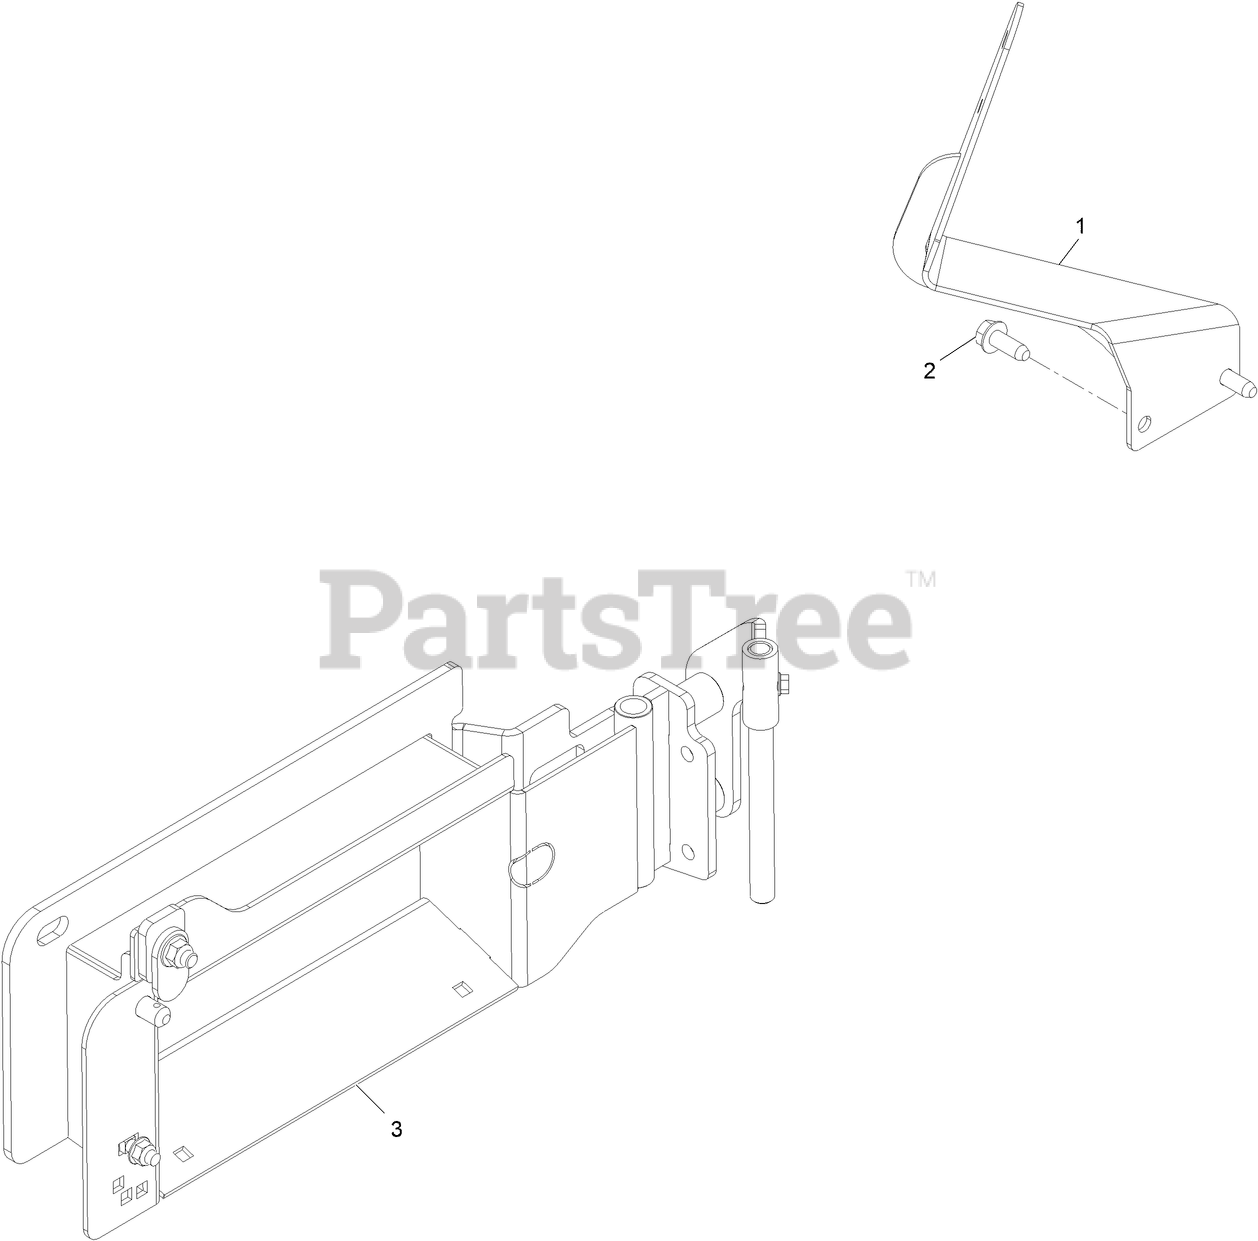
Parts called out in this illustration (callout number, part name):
1	MOUNT-HANDLE OCDC
2	SCREW-FORMING, THREAD
3	KIT-ADAPTOR, ACCY. (SERIES 3)
